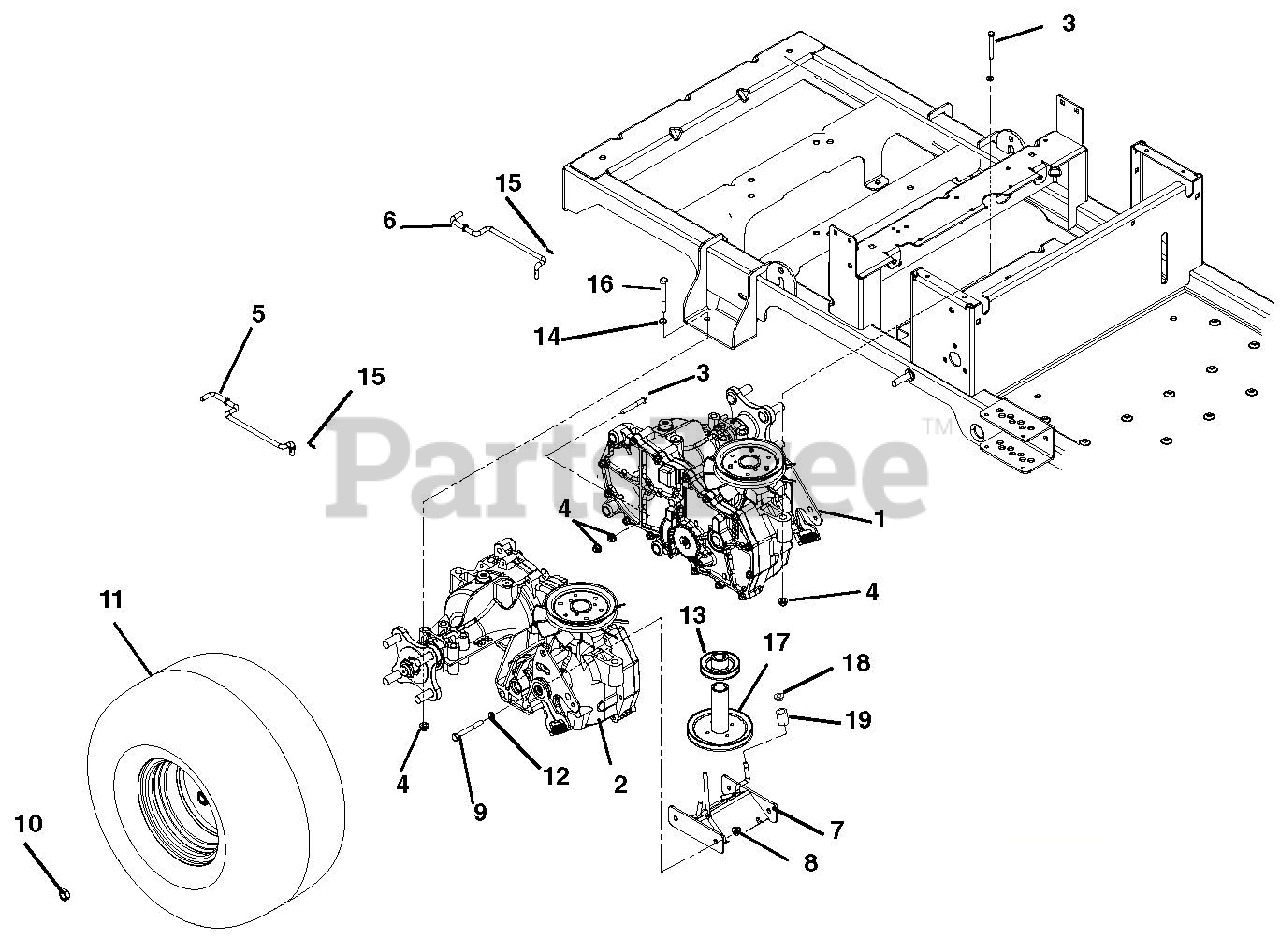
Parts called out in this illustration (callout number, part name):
1	TRANSAXLE, LH EZT SHORT
2	TRANSAXLE, RH EZT SHORT
3	@BLT-HEX .31-18X2.25 GR5 YWZC
4	@NUT-LK-NYL-FLG .31-18 YWZC
5	DUMPVALVE, RH LCZ
6	DUMPVALVE, LH LCZ
7	WMT, TRANSAXLE BRACE
8	@NUT-LK-NYL-FLG .38-16 YWZC
9	@BLT-HEX .38-16X2.50 GR5 YWZC
10	WHEEL NUT .500-20 YZ
11	TIRE-ASM 18X6.5-8 2 PLY OFFSET
12	WSHR-FL-STL .406X1.00X.188 YWZ
13	WMT-SHEAVE, GROUND DRIVE
14	@WSHR-FL-STL.38X.875X.083 YWZC
15	PIN-HAIR INT .06X.18X.77
16	@BLT-HEX .31-18X2.75 GR5 YWZC
17	WMT-SHEAVE, PTO DRIVE
18	NUT-PUSH .312
19	SPACER-.75X.335X.75
